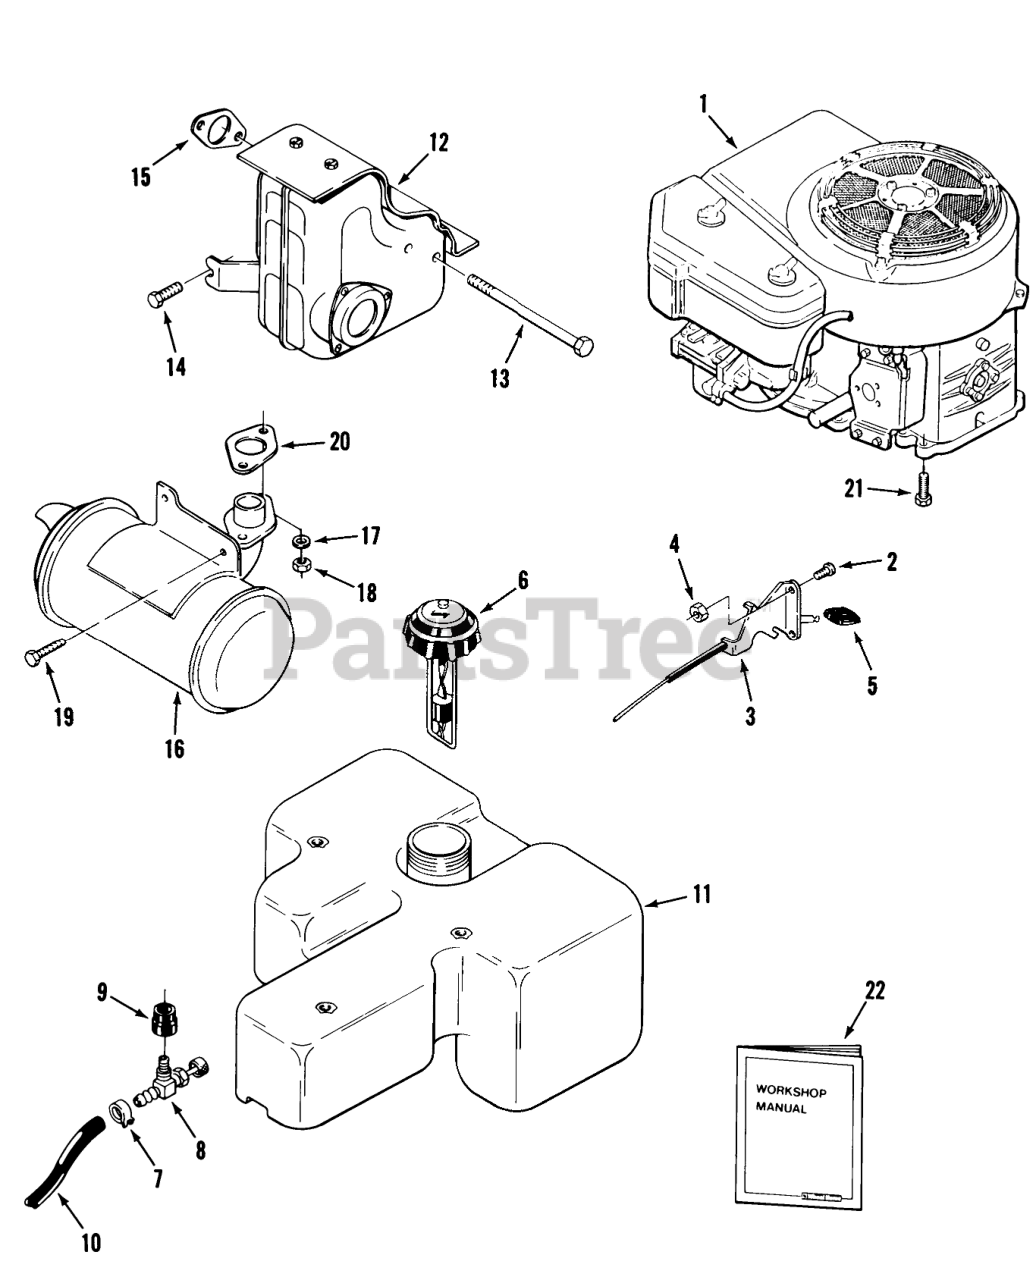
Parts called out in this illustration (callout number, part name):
1	Engine-12.5 HP-Kawasaki Model FB460V, Type AS-26 252-H
1	Engine-17 HP-Kawasaki Model FC540V, Type AS-08 257-H
2	Screw
3	Choke/Throttle Control
4	Nut
5	KNOB-THROTTLE
6	ASS'Y-GAUGE CAP
7	Clamp
8	VALVE-FUEL
9	BUSHING
10	Fuel Hose 54 in. (137.2 cm)
11	Fuel Tank
12	MUFFLER-FB-460V
14	BOLT-FLANGED
15	GASKET-L MUFFLER
16	Muffler 257-H
17	Lockwasher
18	Nut M8x1.25 257-H
19	HHCS M8X1.25X15
20	OBS GASKET-EXH FC-540V
21	BOLT-FLANGED
